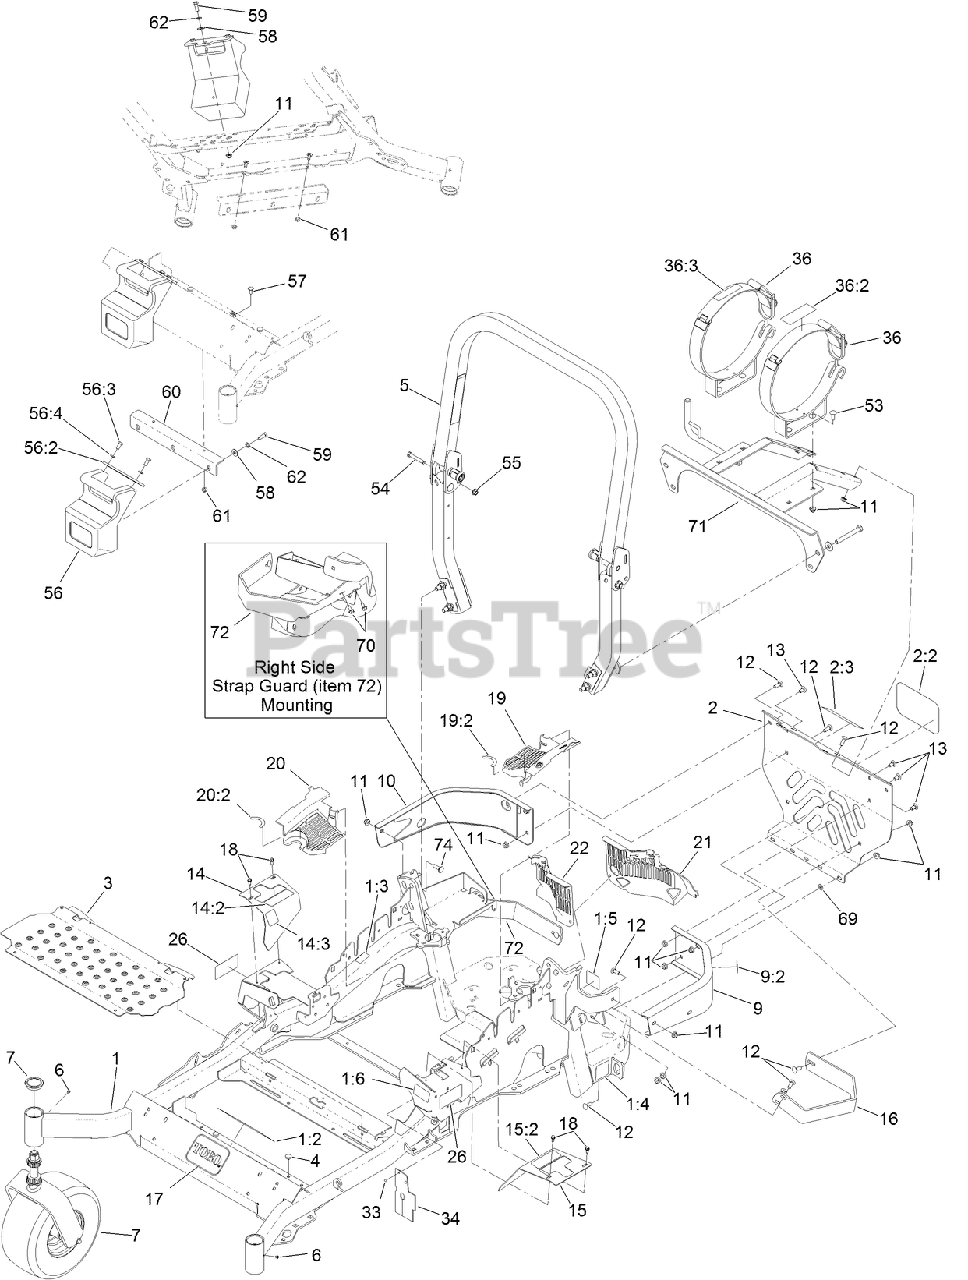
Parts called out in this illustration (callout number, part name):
1	MAINFRAME ASM
1:2	DECAL-CAUTION
1:3	DECAL-SLOPE
1:4	DECAL-BELT DRIVE
1:5	DECAL-SPARK ARRESTER
1:6	DECAL-FUEL FILL
2	LPG REAR GUARD ASM
2:2	DECAL
2:3	DECAL-TANK REPLACEMENT
3	FLOORPAN
4	BUMPER
5	ROPS ASM
7	Caster Wheel ASM
9	LH BUMPER ASM
9:2	DECAL-CAUTION
10	BUMPER-RH
11	NUT-HF, NI
12	SCREW-CARR
13	SCREW-CARR
14	RH MOTION CONTROL COVER ASM
14:2	DECAL-MOTION CONTROL
14:3	DECAL-PARK BRAKE
15	LH MOTION CONTROL COVER ASM
15:2	DECAL-MOTION CONTROL
16	GUARD-MUFFLER
17	DECAL
18	SCREW-HWH
19	LH HYDRO GUARD ASM
19:2	DECAL-HYDRO OIL
20	RH HYDRO GUARD ASM
20:2	DECAL-HYDRO OIL
21	GUARD-HYDRO, REAR (LH)
22	GUARD-HYDRO, REAR (RH)
33	RIVET-POP
34	DEFLECTOR-AIR FLOW
36	TANK BRACKET ASM (SET)
36:2	DECAL-LPG WARNING
36:3	DECAL-LPG 43.5LB TANK
53	BOLT-CARR
54	SCREW-HH
55	NUT-LOCK
56	WEIGHT ASM
56:2	TAB-SUPPORT, WEIGHT
56:3	SCREW-HH
56:4	WASHER-LOCK
57	SCREW-CARR
58	WASHER-FLAT
59	SCREW-HH
60	BRACKET-MOUNT, WEIGHT
61	NUT-HF, NI
62	WASHER-LOCK
69	NUT-PUSH
70	SCREW-HWHTF
71	SUPPORT-LPG TANK
72	STRAP-GUARD
74	BOLT-CARR
